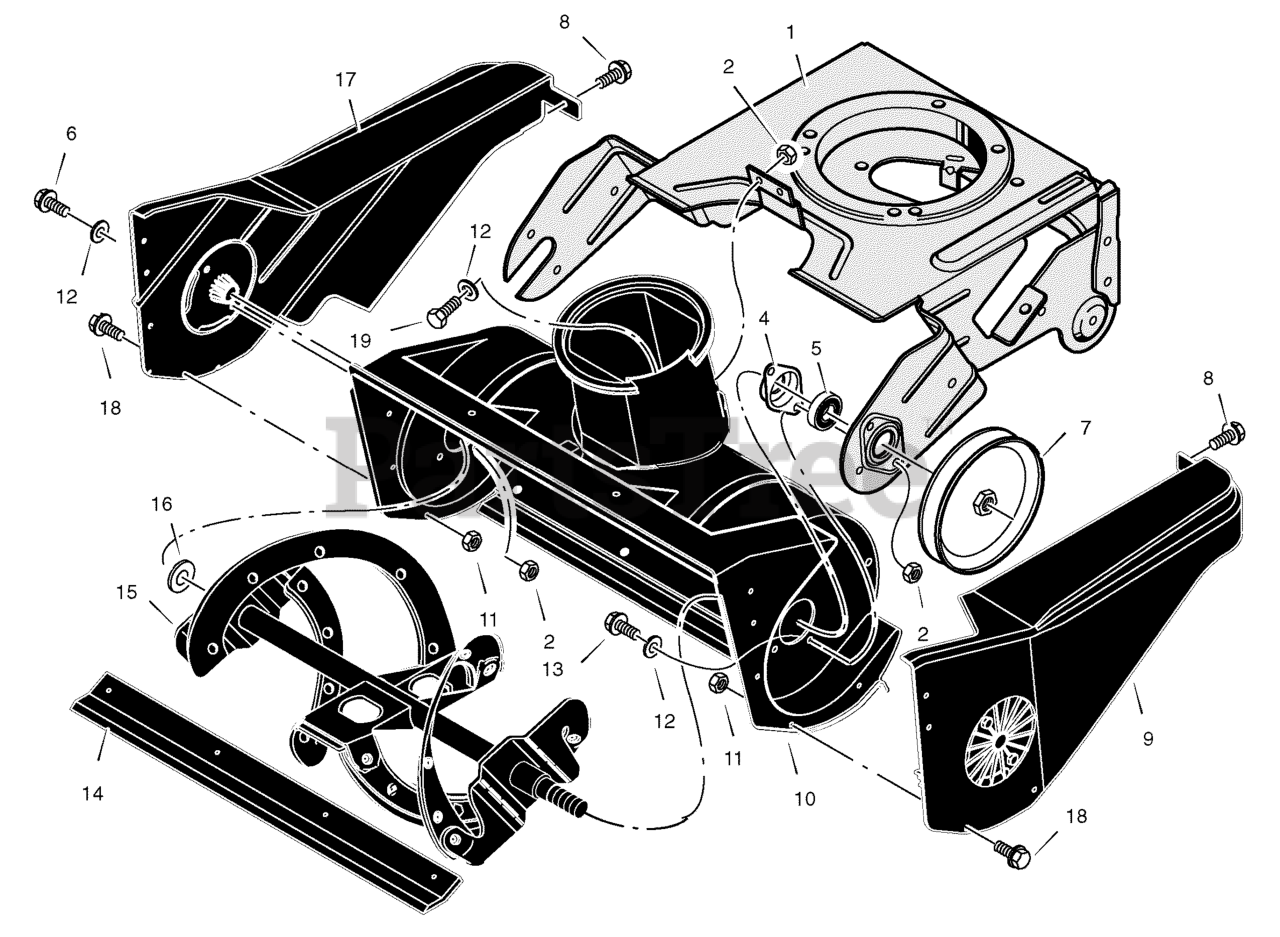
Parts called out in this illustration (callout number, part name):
1	Frame, Motor Box
2	Nut
4	Retainer, Bearing
5	Bearing
6	Bolt
7	Pulley, Auger
8	Screw
9	Cover, Left Belt
10	Assembly, Auger Housing
11	Nut
12	Washer
13	Bolt
14	Blade, Scraper
15	Auger Assembly
16	Washer
17	Cover, Right
18	Screw
19	Screw
